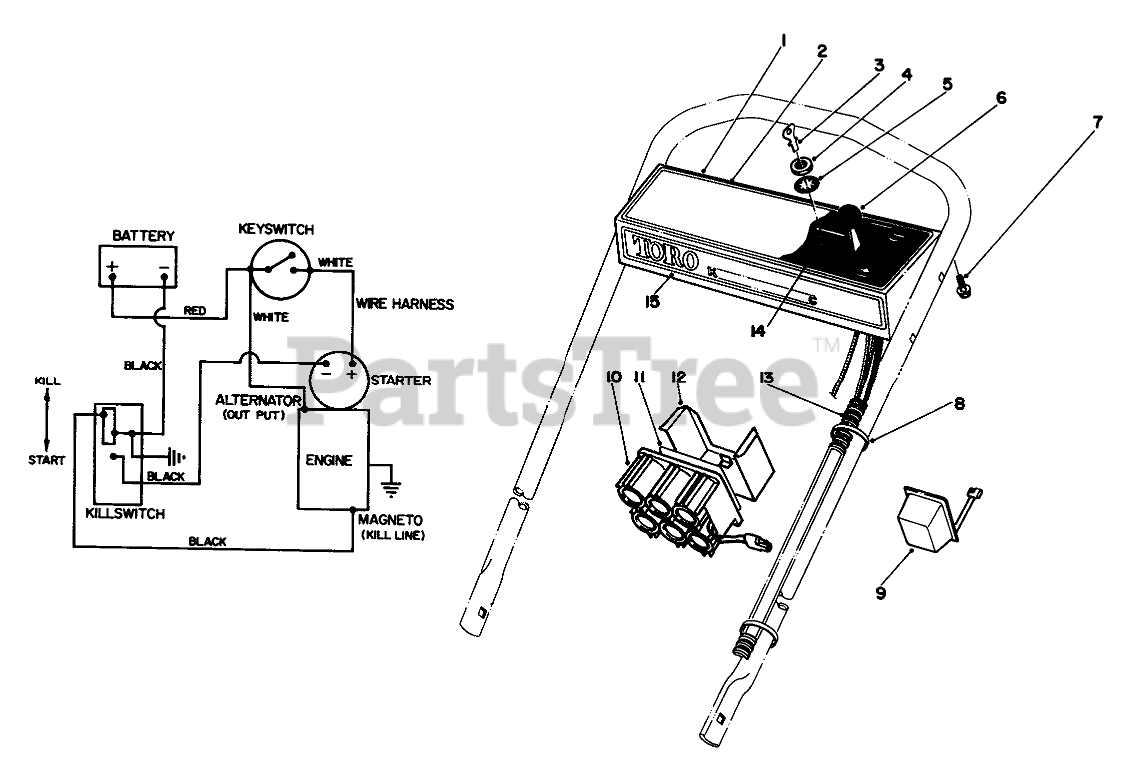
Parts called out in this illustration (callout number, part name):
1	Control Panel (Incl. Ref. #2)
2	Decal-Instructions
3	Key
4	NUT-HH
5	Lockwasher
6	SERVICE THROTTLE CONTRO
7	SCREW-HWHTF
8	TIE-CABLE
9	Charger
10	BATTERY ASSEMBLY
11	Decal
12	Retainer-Battery
13	WIRE HARNESS
14	Switch-Starter (Incl. Ref. #4 8 5)
15	Decal-Toro
